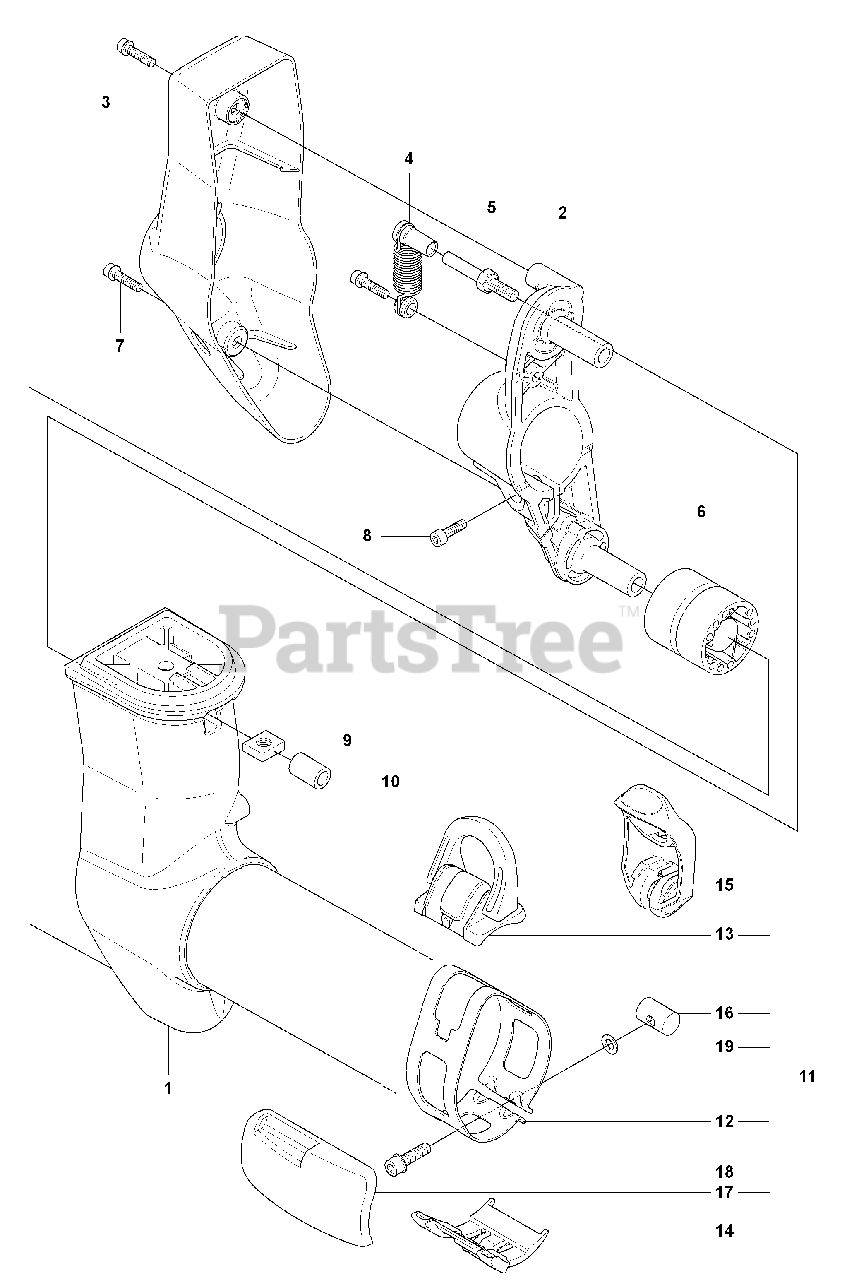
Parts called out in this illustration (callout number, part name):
1	SUSPENSION
4	SPRING
5	PARALLEL PIN
6	ANTIVIBE ELEMENT
7	SCREW IHSCFM
14	GUIDE RAIL
17	WEAR PROTECTION
19	WASHER 5.3X12
